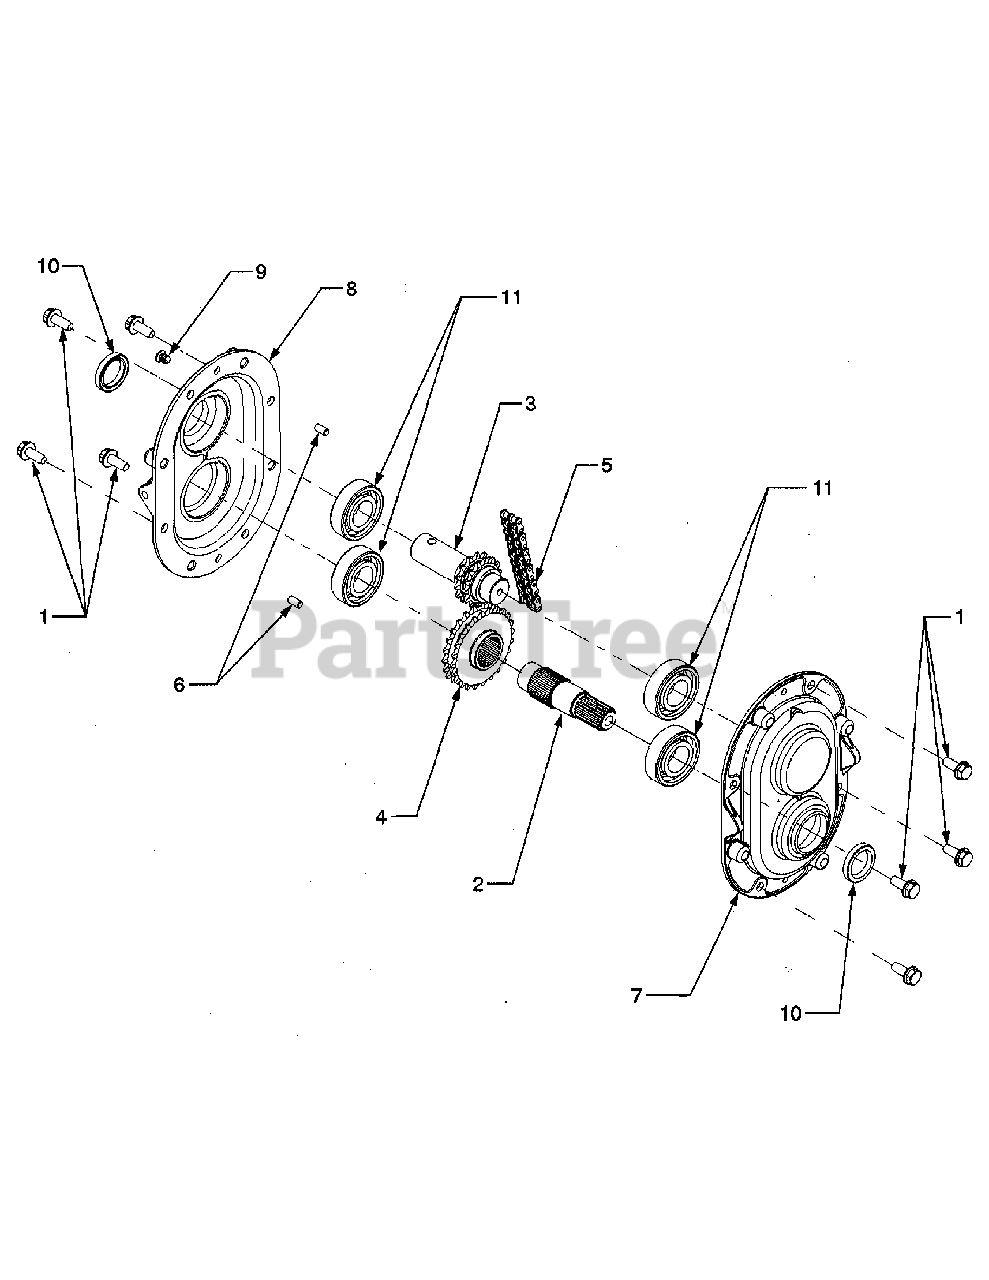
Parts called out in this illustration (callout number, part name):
1	Screw. Hex Wash . Hd . Tapp 5/16-18 x .75
2	Shaft. Output
3	Shaft. Input (w/ sprocket)
4	Sprocket. Drive
5	Chain. Endless. #35-2 x 34 Links
6	Dowel Pin. 114 x 112
7	Housing. Gear
8	Housing. Gear
9	Plug. 114 x . 437
10	Seal. Oil
11	Bearing. Ball
